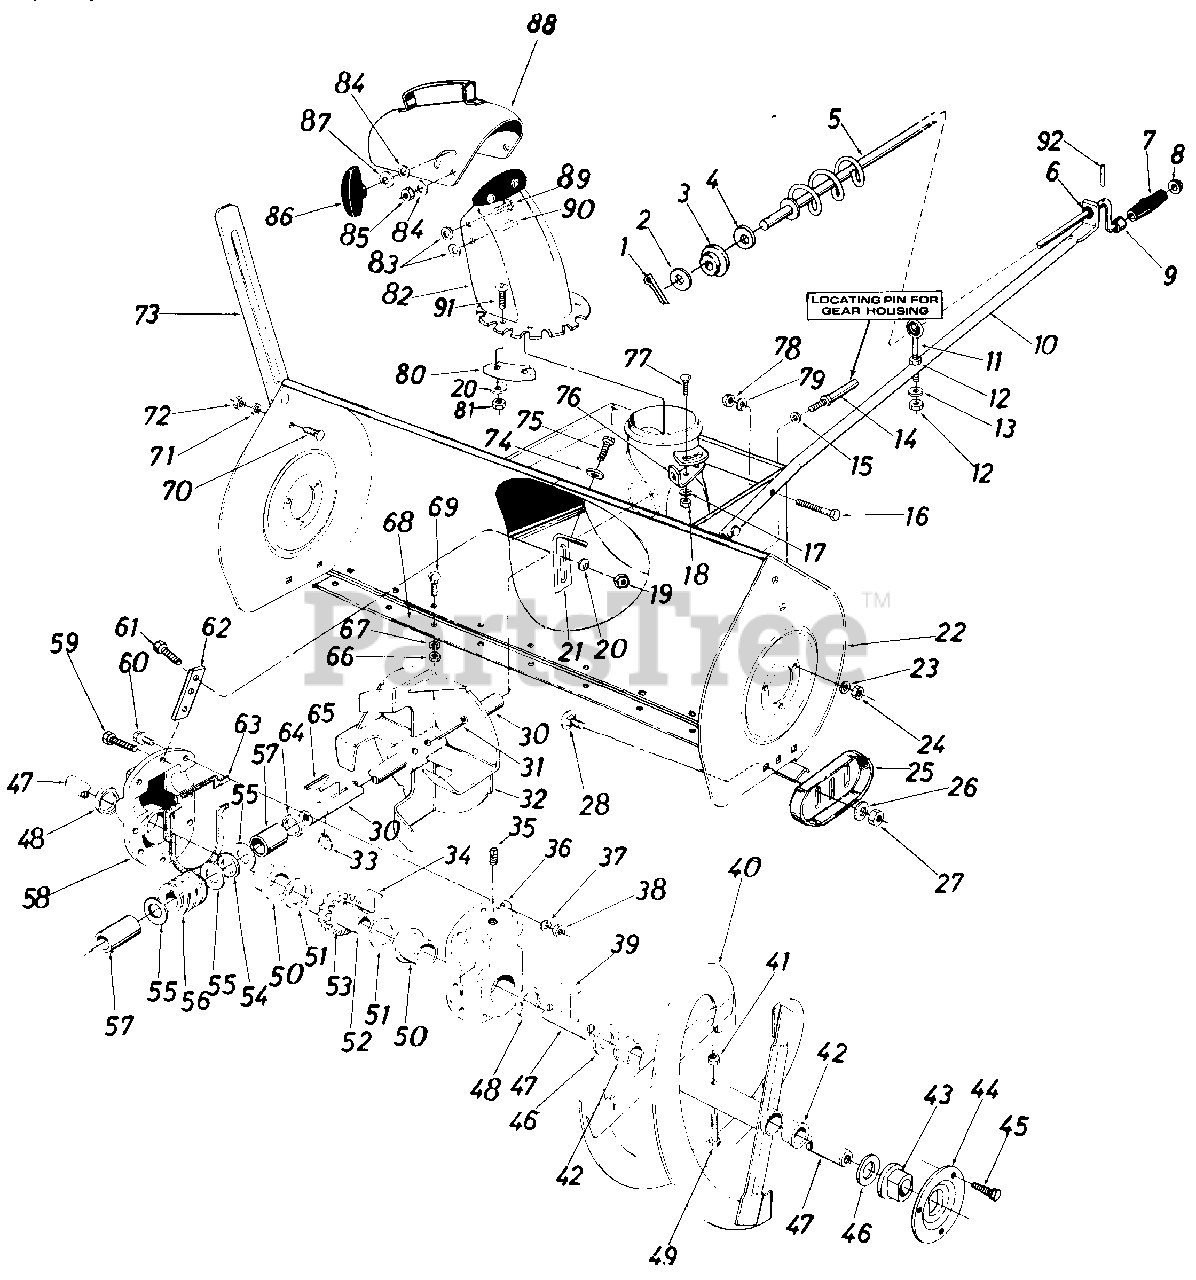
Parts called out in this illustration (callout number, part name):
1	Cotter Pin
2	Fl.-Wash. .39" I.D. x .62" O.D.
3	Plastic Bushing
4	Fl.-Wash. .385" I.D. x .62" O.D.
5	Chute Crank Ass'y.
6	Plastic Bushing
7	Knob (Black)
8	Push Nut 3/8" Rod
9	Spacer .385 I.D. x .50" I.D.
10	Chute Crank Support Tubing
11	Eyebolt
12	Hex Nut 5/16-18 Thd.
13	Bell.-Wash. .345" I.D. x .88" 0.D.
14	Stud 3/8-16 x 2.75" Lg.
15	Bell.-Wash. .400" I.D. x .88" 0.D.
16	Hex Bolt 3/8-24 x 1.25" Lg.
17	Bell.-Wash. .345" I.D. x .88" 0.D.
18	Hex Nut 5/16-18 Thd.
19	Hex Nut 1/4-28 Thd.
20	Bell.-Wash. .265" I.D. x .75" 0.D.
22	45" Snow Blower Housing Ass'y
23	L.-Wash. 5/16" I.D.
24	Hex Nut 5/16-18 Thd.
25	Slide Shoe
26	Bell.-Wash. .400" I.D. x .88" 0.D.
27	Hex Jam Nut 3/8-16 Thd.
28	Carriage Bolt 3/8-16 x .62" Lg.
30	Blower Axle .875" Dia. x 14.75" Lg.
31	Spring Pin Spir. 5/16" Dia. x 1.75" Lg.
34	#91 Woodr-Key 1/4 x 3/4" Dia. (HDN)
35	Vent Plug
36	Comp. Gear Hsg. Half-L.H.
37	Spr.-Wash. .32" I.D. x .62" O.D
38	Hex Ins. L.-Nut 5/16-18 Thd.
39	#91 Woodr-Key 1/4 x 3/4" Dia. (HDN)
41	Hex Ins. L.-Nut 5/16-18 Thd.
42	Plastic Bushing
43	Flange Brg. w/flats 1" I.D.
44	Bearing Housing
45	Hex Sems Bolt 5/16-18 x .75" Lg.
46	Fl.-Wash. 1.00" I.D. x 1.75" O.D
47	Spiral Axle
48	Flange Bearing 1.503" I.D.
49	Shear Bolt 5/16-18 x 1.75" Lg.
50	Oil Seal 1.50" I.D.
51	Fl.-Wash. 1.50" I.D. x 2.00 " O. D
52	Worm Gear Shaft
53	Double Threaded Worm Gear-L.H.
54	Thrust Brg.-.88" I.D. x 1.44" 0. D.
55	Fl.-Wash. .88" I.D. x 1.4" 0.D.
56	Double Threaded Worm-L.H.
57	Sleeve
58	Complete Gear Hsg. Half-R.H.
59	Hex Bolt 5/16-18x 1.25" Lg.
60	Hex Bolt 5/16-18 x 1.0" Lg. (Grade 5)
61	Hex Bolt 1/4-28 x .75" Lg.
62	Gear Housing Support Plate
63	Rubber Gasket
64	Oil Seal-.875" I.D.
65	#9 Hi-Pro Key 3/16 x 3/4" Dia. (HT.)
66	Hex Nut 5/16-18 Thd.
67	L.-Wash. 5/16" I.D.
69	Carriage Bolt 5/16-18 x 1.00" Lg.
70	Carriage Bolt 5/16-18 x .62" Lg.
71	L.-Wash. 5/16" I.D.
72	Hex Nut 5/16-18 Thd.
73	Guide Blade
74	Bell.-Wash. .345" I.D. x .88" O.D.
75	Hex Wash. Hd. AB Tap Scr. 5/16 x .75" Lg.
77	Carriage Bolt 5/16-18 x.75" Lg.
78	Hex Ins. L.-Nut 3/8-24 Thd.
79	L.-Wash. 3/8" I.D.
80	Chute Flange Keeper
81	Hex L-Nut 1/4-20 Thd.
82	Chute Ass'y. w/Chute Guard
83	Fl.-Wash. .285" I.D. x 1.25" O.D.
84	Bell.-Wash. .345" I.D. x .88" 0.D.
85	Hex Cent. L.-Nut 5/16-18 Thd.
86	Knob Handle
87	Bell.-Wash. .345" I.D. x .88" O.D.
88	Top Chute Ass'y.
89	Carriage Bolt 5/16-18 x 1.00" Lg.
90	Carriage Bolt 5/16-18 x .62" Lg.
91	Truss Mach. Scr. 1/4-20 x .75"
92	Roll Pin .12 Dia. x .63"
